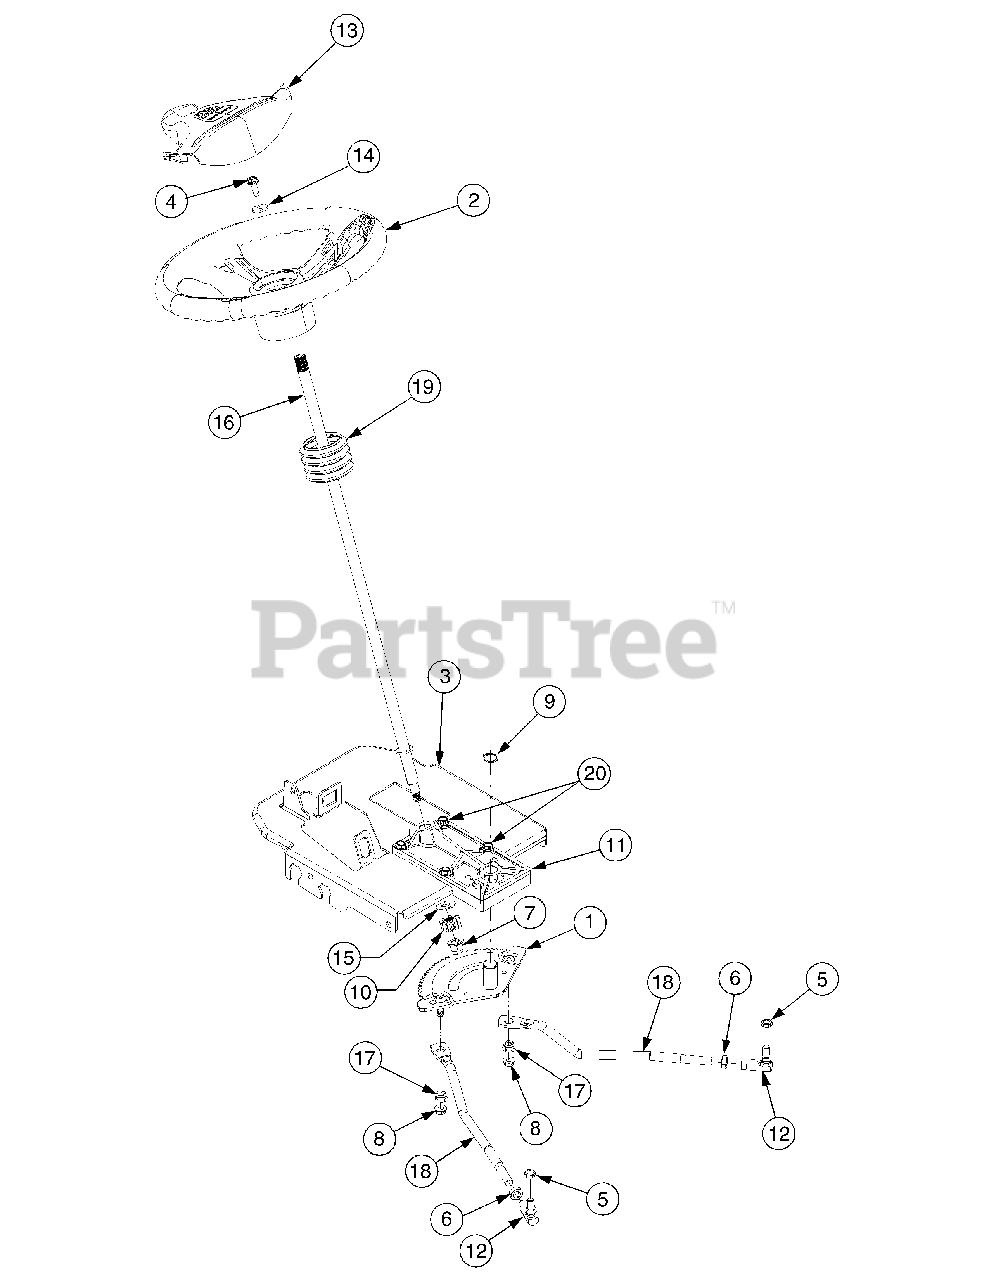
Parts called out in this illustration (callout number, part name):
1	Gear Assy, Segment
2	Wheel, Steering, Soft Grip
4	Screw, Hx. Wash. Hd Tapp, 5/16-18 x .875 (S.N. K016 and After)
5	Nut,Hex Center Lock, 3/8-24 GrB (S.N. K016 and Before)
5	Nut, Hex Jam Lock, 3/8-24 Gr2 (S.N. K016 and After)
6	Nut, Hex Jam, 7/16-20 GR2
7	Nut, Flange Lock 7/16-20 GrB
8	Nut, Hex Flange Lock, 5/16-18 GR5
9	Ring, Snap, .75 Dia Shaft
10	Gear, Steering Pinion
11	Housing Assy, Steering
12	Joint, Ball, 3/8-24
13	Cover, Steering Wheel
14	Washer, Flat, .406 x .875 x .105 Thk
15	Washer, Flat, .51 x 1.12 x .03 Thk
16	Shaft, Steering, .625 x 27.10
17	Plastic Bushing, .38 ID
18	Link, Drag
19	Bellow, Steering, 2.12 Lg
20	Screw, Hx. Wash. Hd Tapp, 5/16-18 x .75 (S.N. K016 and Before)
20	Screw, Hx. Wash. Hd Tapp, 5/16-18 x 1.0 (S.N. K016 and After)
